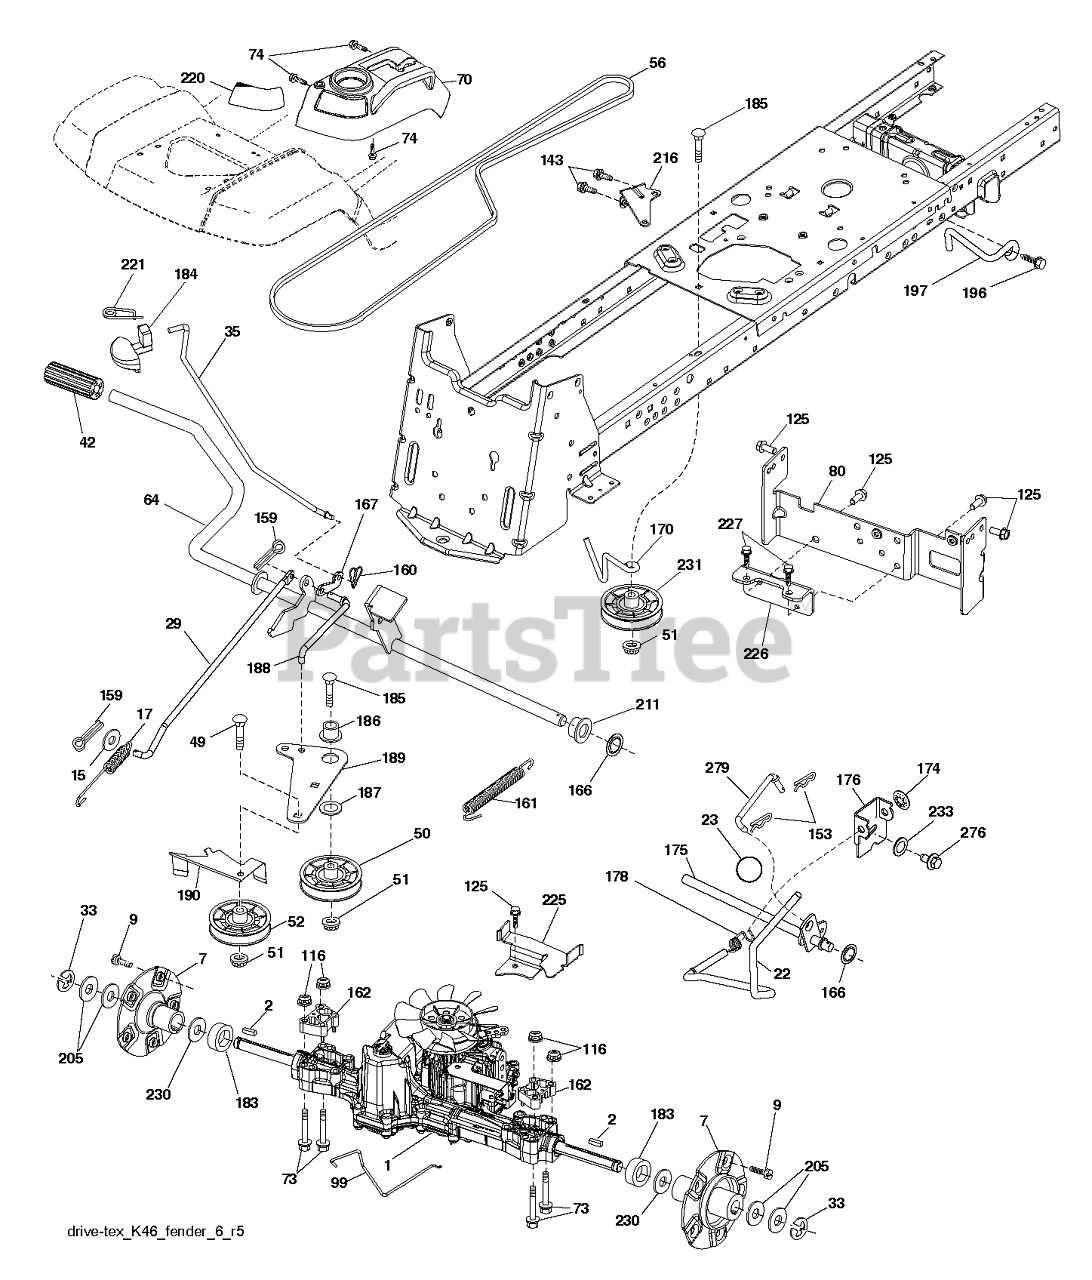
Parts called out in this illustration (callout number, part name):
2	KEY.SQUARE.187X2.500
7	HUB.ASM.WHEEL.REAR.22"
9	HUB BOLT
15	WASHER
17	SPRING.BRAKE.K46.GREEN
22	ROD.SHIFT.FENDER.STGT.
23	KNOB.DELUXE.(PISTOL.GRIP).BLAC
29	ROD.BRAKE.K46
33	E-RING LT
35	ROD.BRAKE.PARTK.HUSQ.TEX
42	PEDAL COVER T
49	BOLT
50	IDLER.FLAT.910.OFFSET
51	NUT LOCK FLG 3/8-16 UNC
52	IDLER.V-GROOVE.910.OFFSET
56	V-BELT.MOWER.92.40.42/K46
64	SHAFT.ASM.PEDAL.BRAKE.
70	SUBASM.CONSOLE.HUSQ.GT.HYDRO
73	BOLT.HEX.FLNG.5/16-18X3.75
74	SCREW.HI-LO.CONSOLE
80	STRAP.TORQUE.K46.K57R.TT
99	ROD.SPRING.BYPASS.K46.TEX.GT
116	NUT LOCK HEX FLANGE 5/16-18
125	SCREW
143	SCREW LT
153	RETAINER M
159	COTTER PIN
160	RETAINER CLIP
161	SPRING, RETURN LT
162	SPACER.TRANSAXLE.18&22
166	NUT.PUSH.625
167	LATCH.BRAKE.SPRING
170	KEEPER.CENTER SPAN.1.688
174	NUT.PUSH.500.2006
175	SHAFT ASM SHIFT
176	ARM.CLEVIS.ROD.SHIFT
178	SPRING.SHIFT.GT2006
183	SPACER.SPLIT.800X.350
184	RB HANDLE.PARKG.BRK.HUS/PRED
185	BOLT
186	SPACER.RETAINER
187	WASHER 12/32X2X10GA
188	RP LINK.CLUTCH.GROUND.DRIVE
189	BELLCRANK.GROUND.DRIVE.TEX.
190	KEEPER.BELLCRANK.DRIVE
196	SCREW 3/8-16X1
197	BRKT.ANIT-ROTATION.CLUTCH
205	WASHER
211	BUSHING.SHAFT.BRAKE.HAND
216	BRACKET.PULLEY.IDLER.W/TEX
220	REFLECTOR.RH.TEX GT
221	RETAINER.SPRING.CLIP.H
225	KEEPER.BELT.TRANSAXLE.K46
226	BRKT.MOUNT.TORQUE.K46.
227	SCREW
230	WASHER.HARDENED
231	IDLER.V-GROOVE.1.688.OFFSET
233	WASHER SERRATED
276	BOLT FIN HEX 7/16-14 X 1
279	LINK.SHIFT.T/A.K46.FEND.TX
